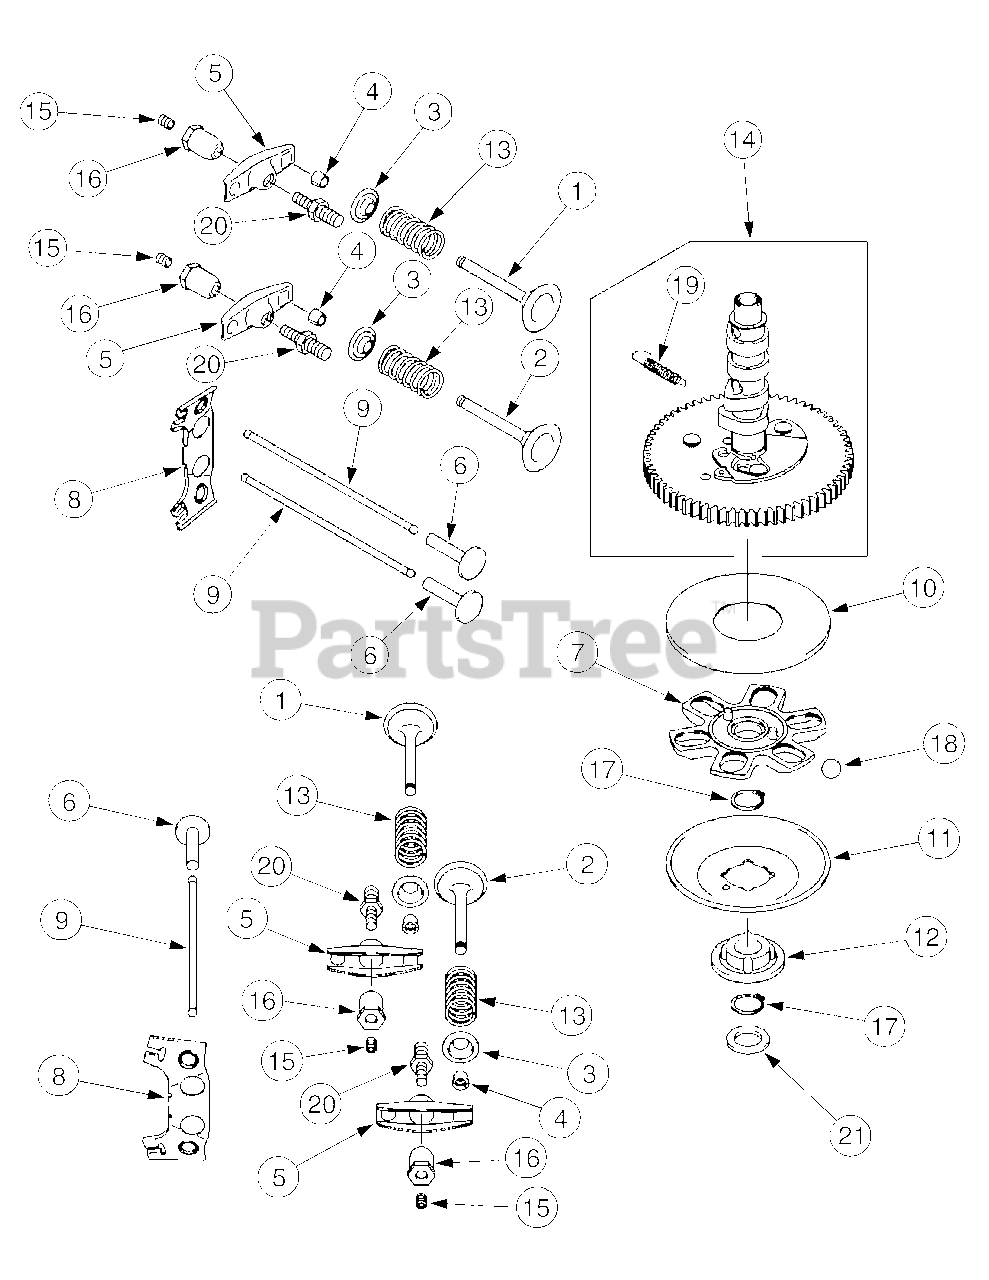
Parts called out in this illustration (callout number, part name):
1	Valve, Intake
2	Valve, Exhaust
3	Retainer, Valve Spring
5	Arm, Rocket
11	Plate, Governor
12	Sleeve
13	Spring, Valve
14	Camshaft, Complete
17	Ring, Snap
18	Ball
19	Spring
